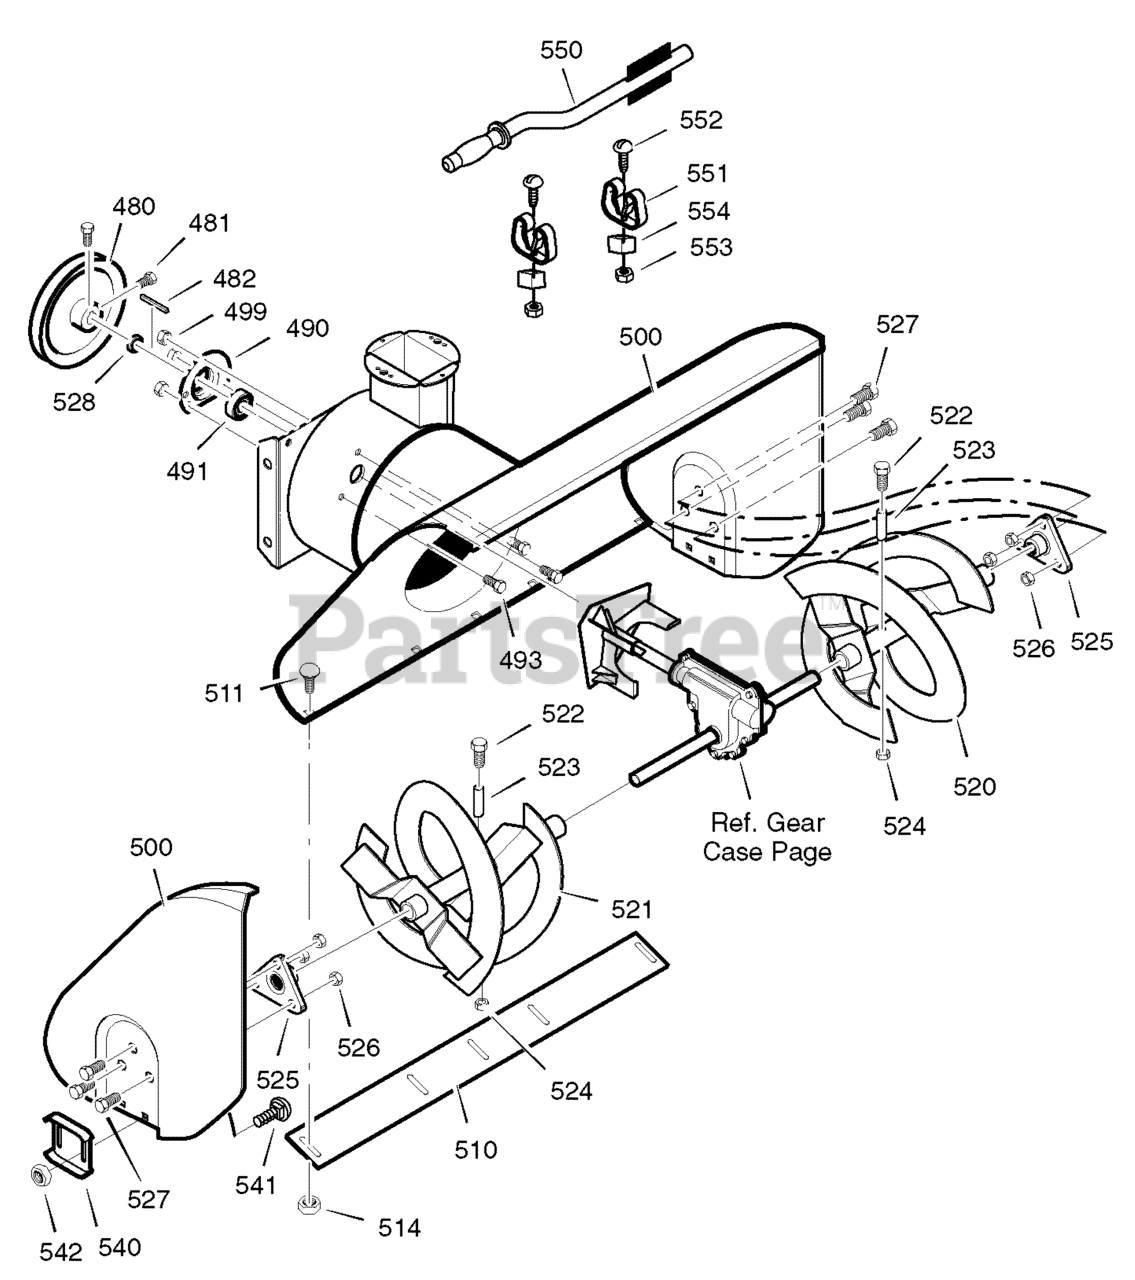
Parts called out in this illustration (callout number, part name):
480	PULLEY, V4L 8.4X .67
481	SCREW, 5/16-18 X .63
482	KEY, SQUARE 3/16 X 3/4
485	SPACER, FRICTION PULLEY
490	RETAINER, BALL BRNG
491	BEARING, BALL
493	BOLT, HEX 5/16-18 X 1/2
499	NUT, 5/16-18 HEX
500	HOUSING, ASSY
510	BLADE, SCRAPER
511	BOLT, 5/16-18 X 3/4
514	NUT, 5/16-18
520	AUGER, ASSY, LH
521	AUGER, ASSY, RH
522	SCREW
523	SPACER, SLEEVE
524	NUT, 1/4-20
525	BEARING, FLANGE
526	NUT, 5/16-18
527	SCREW, 5/16-18 X 3/4
540	SKID, HEIGHT ADJUST
541	BOLT, 5/16-18 X .75
542	NUT, 5/16-18
550	BRUSH, CLEANOUT
551	CLIP, RETAINER
552	SCREW
554	BLOCK
